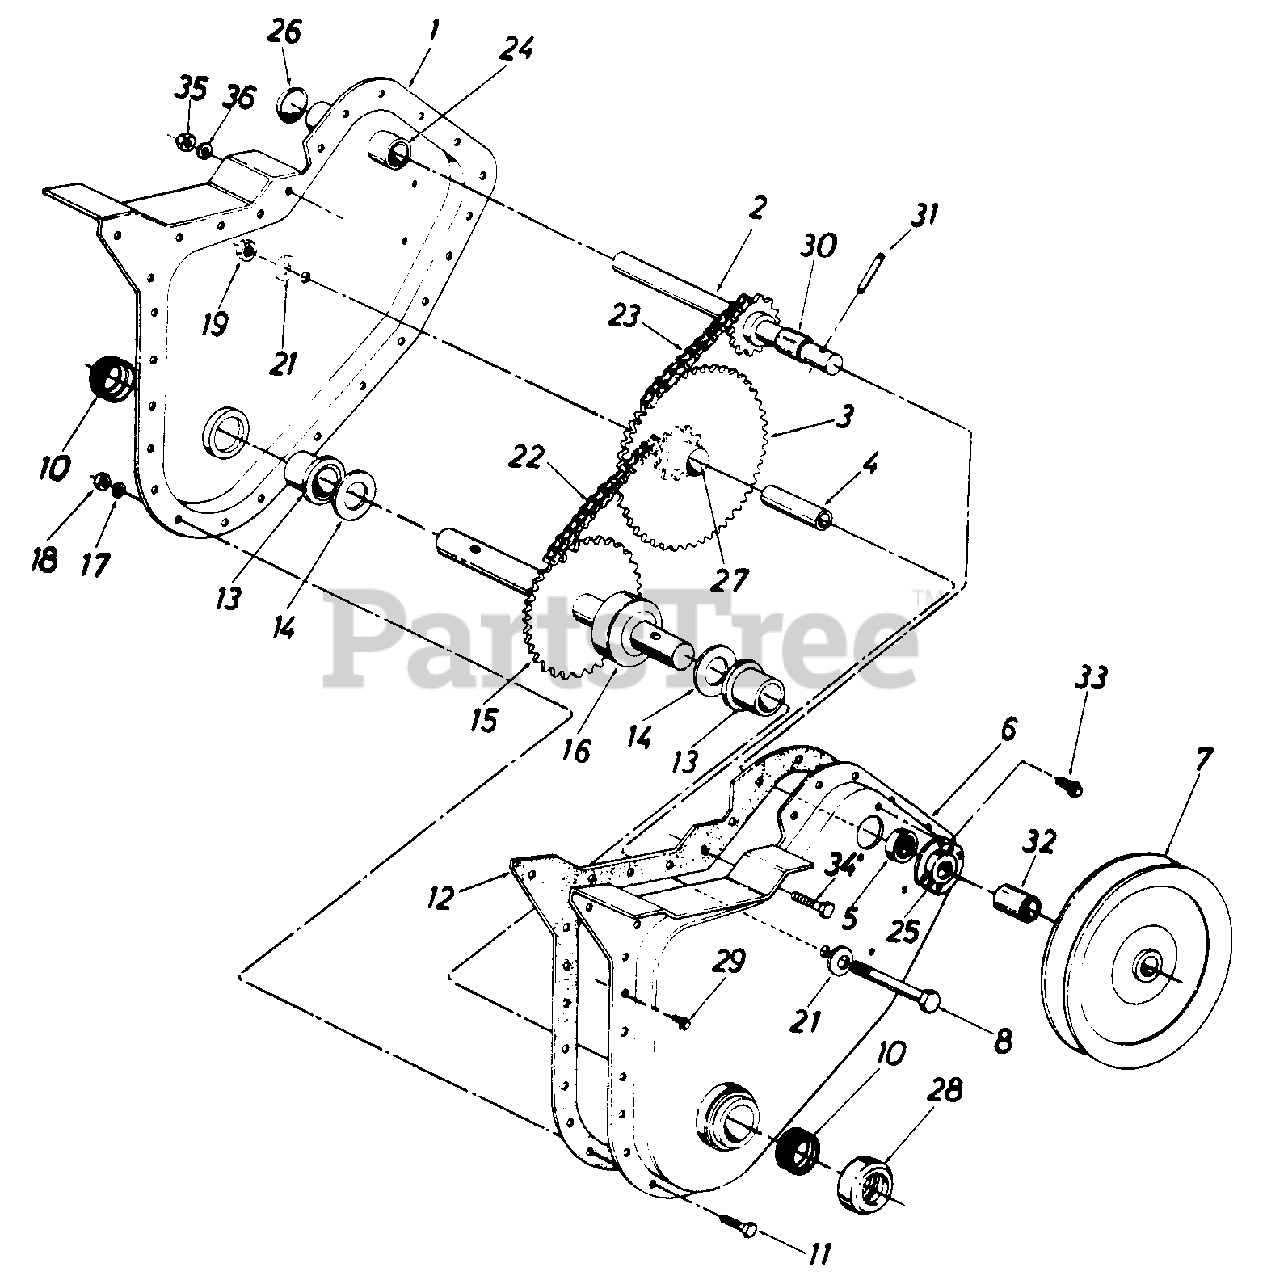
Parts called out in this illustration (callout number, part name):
1	Chain Case Ass'y.--R.H.
2	Input Shaft Ass'y.
3	Hub and Sprocket Ass'y.
4	Bearing Inner Race
5	Ball Bearing
8	Hex Bolt 3/8-24 x 2.5" Lg.
11	Hex Bolt 1/4-28 x .625" Lg.
12	Gasket
13	Flange Brg. .879" I.D.
14	Fl-Wash. .88" I.D. x 1.5"
15	Tine Shaft Ass'y.
16	Spacer 7/8" I.D. x .68" Lg.
17	L-Wash. 1/4" I.D.
18	Hex Nut 1/4-28 Thd.
19	Hex Ins. L-Nut 3/8-24 Thd.
21	Bell-Wash. .406" I.D.
22	Chain #420 1/2" Pitch x 37 Links
23	Chain #35 .375" Pitch x 49 Links
24	Bearing .62" I.D. x .813"
25	Bearing Housing
26	Expansion Plug 13/16" Dia.
28	Dust Cap
29	Hex Wash. Hd. Self-Tap Scr. 1/4-20 x .50" Lg.
30	Spacer .63" I.D. x .77" O.D. x .38" Lg.
31	Spring Pin Spiral 1/4" Dia. x 1 1/2" Lg.
32	Spacer .647 x 1 25"
33	Hex Wash. Hd. Self-Tap Scr. 1/4-20 x .38" Lg.
34	Hex Bolt 5/16-18 x .75" Lg.
35	Hex Nut 5/16-18 Thd.
36	L-Wash. 5/16" I.D.
